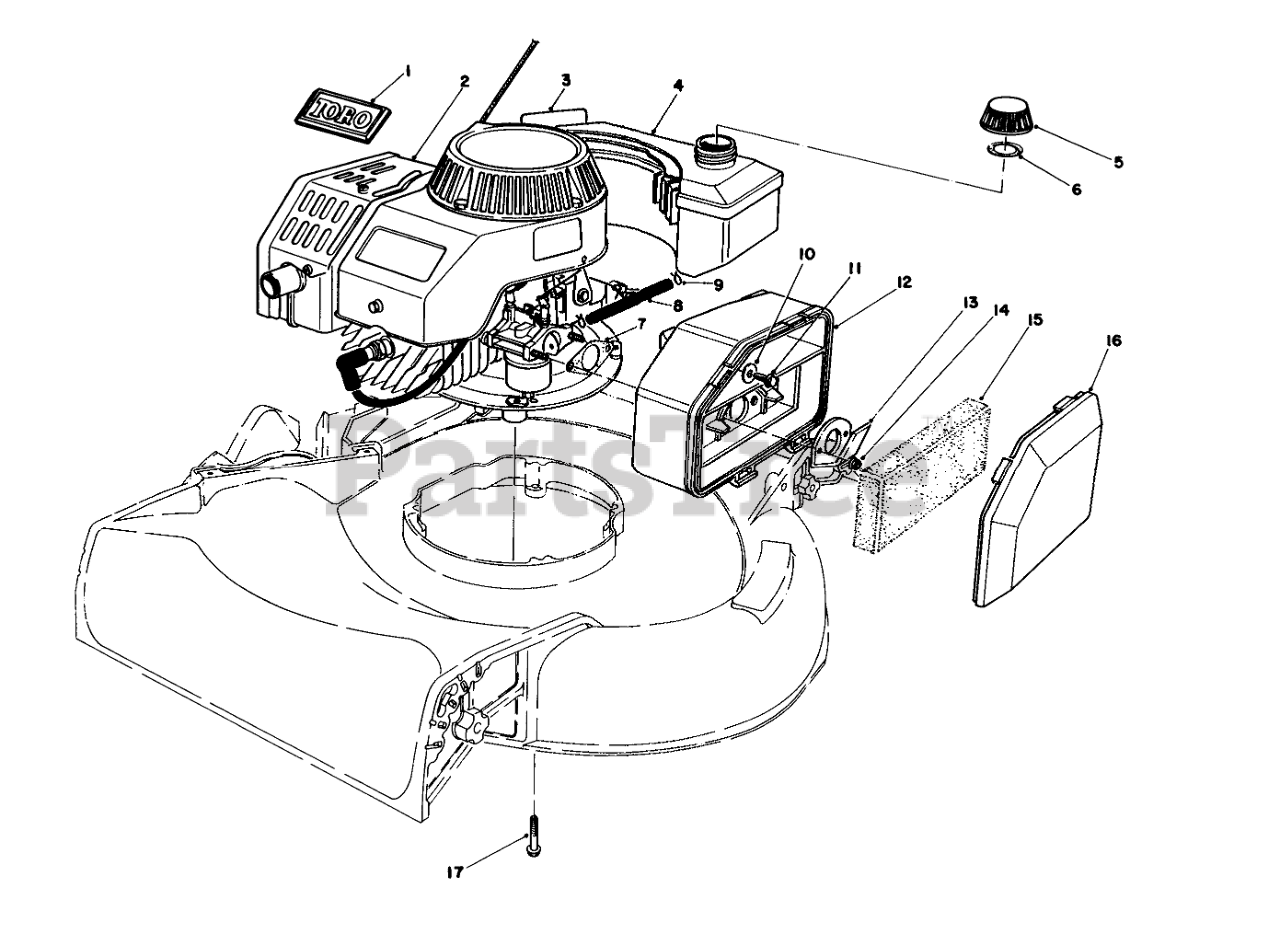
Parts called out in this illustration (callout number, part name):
1	TORO LOGO PLT
2	Engine
3	Decal-Maintenance
4	Fuel Tank Assembly
5	Gas Cap Assembly (Incl. Ref. #6)
6	GAS CAP GASKET
7	GASKET-AIR CLEANER
8	FUEL LINE
9	CLAMP-HOSE
10	WASHER-FLAT
11	SCREW-HH
12	AIR CLEANER
13	SPIT BACK DEFLECTOR
14	NUT-LOCK
15	FILTER
16	AIR CLEANER COVER
17	FLG SCREW,3/8-16X2.000
